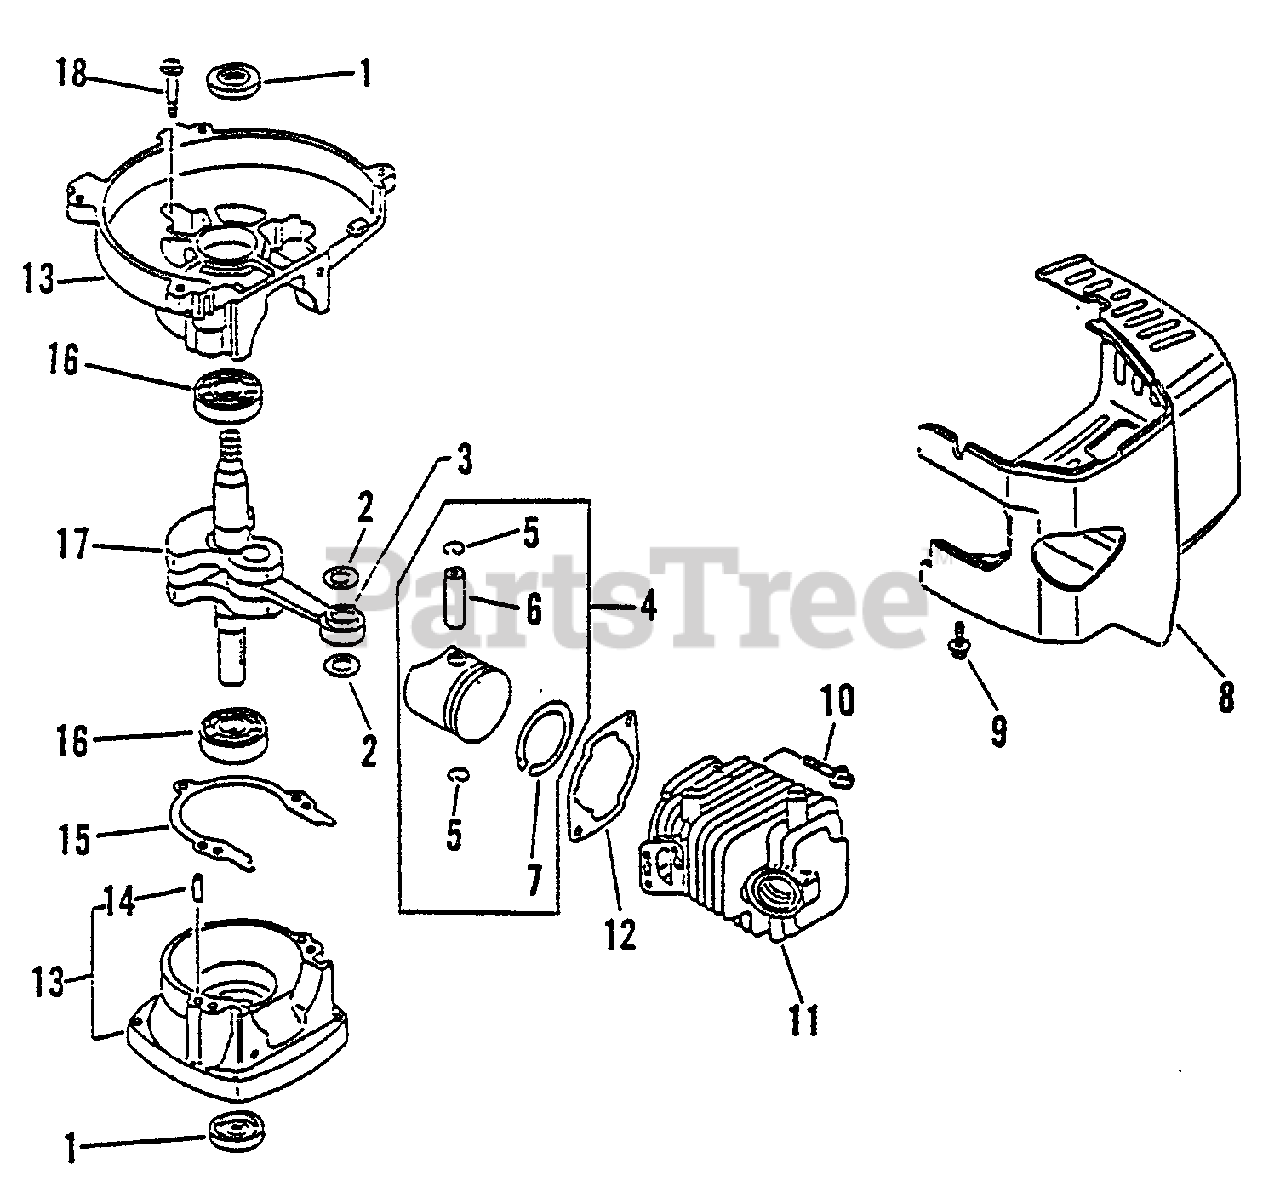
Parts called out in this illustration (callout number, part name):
1	SEAL, OIL 12
2	WASHER, THRUST
3	BEARING, NEEDLE
4	PISTON KIT
5	RING, SNAP
6	PIN, PISTON 8
7	RING, PISTON
8	COVER, CYLINDER
9	SCREW 4×20
10	BOLT 5×22
12	GASKET, CYLINDER
13	CRANKCASE KIT
14	PIN, LOCATING 4
15	GASKET, CRANKCASE
16	BEARING, BALL - 6201 C3
17	CRANKSHAFT
18	SCREW 5×28
